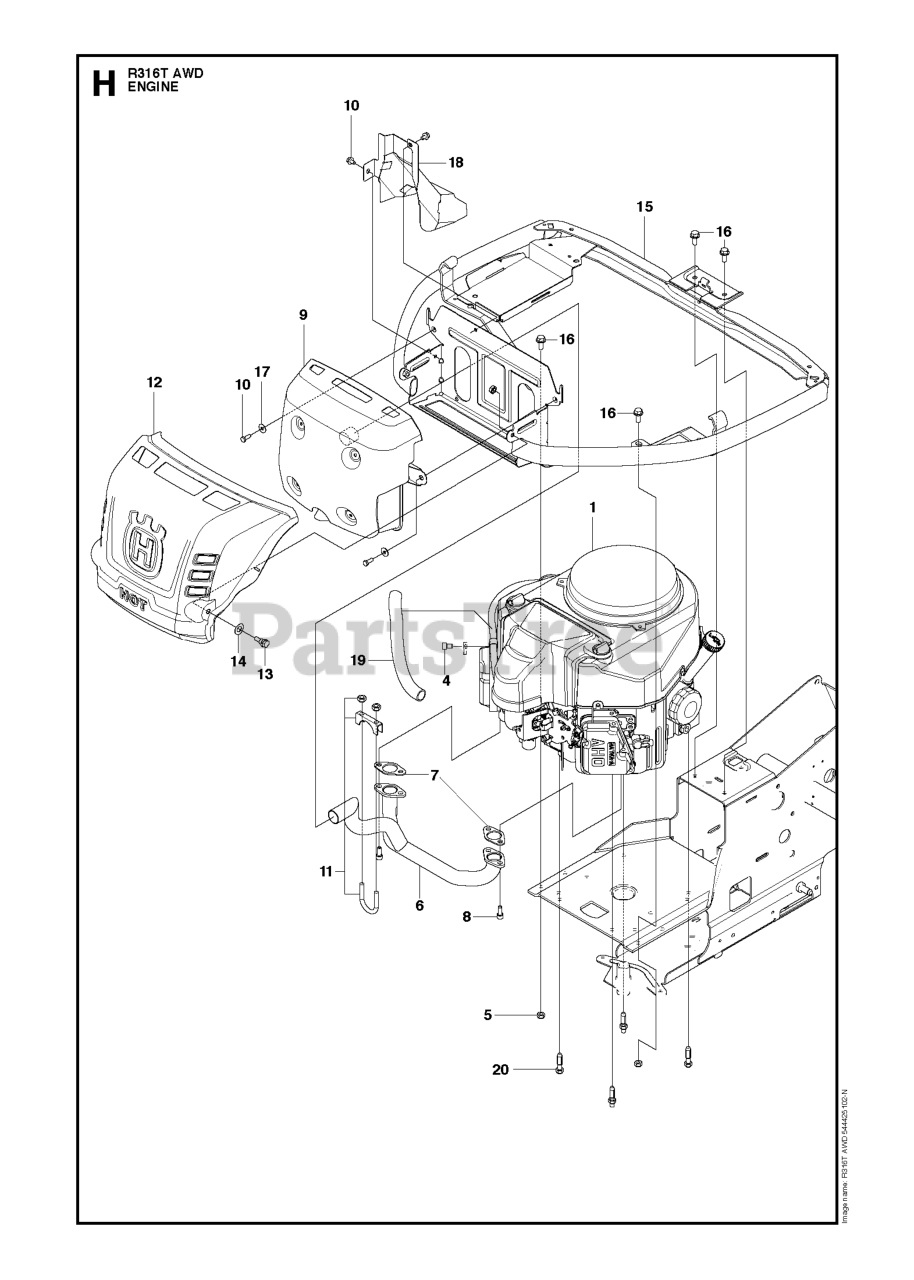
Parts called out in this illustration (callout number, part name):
4	SCREW IHSCM
5	LOCKNUT M8
11	CLAMP
12	HEAT SHIELD
14	SPRINGWASHER
15	ENGINE FRAME
17	WASHER - 26X6.5X1.6
20	STUD SCREW
